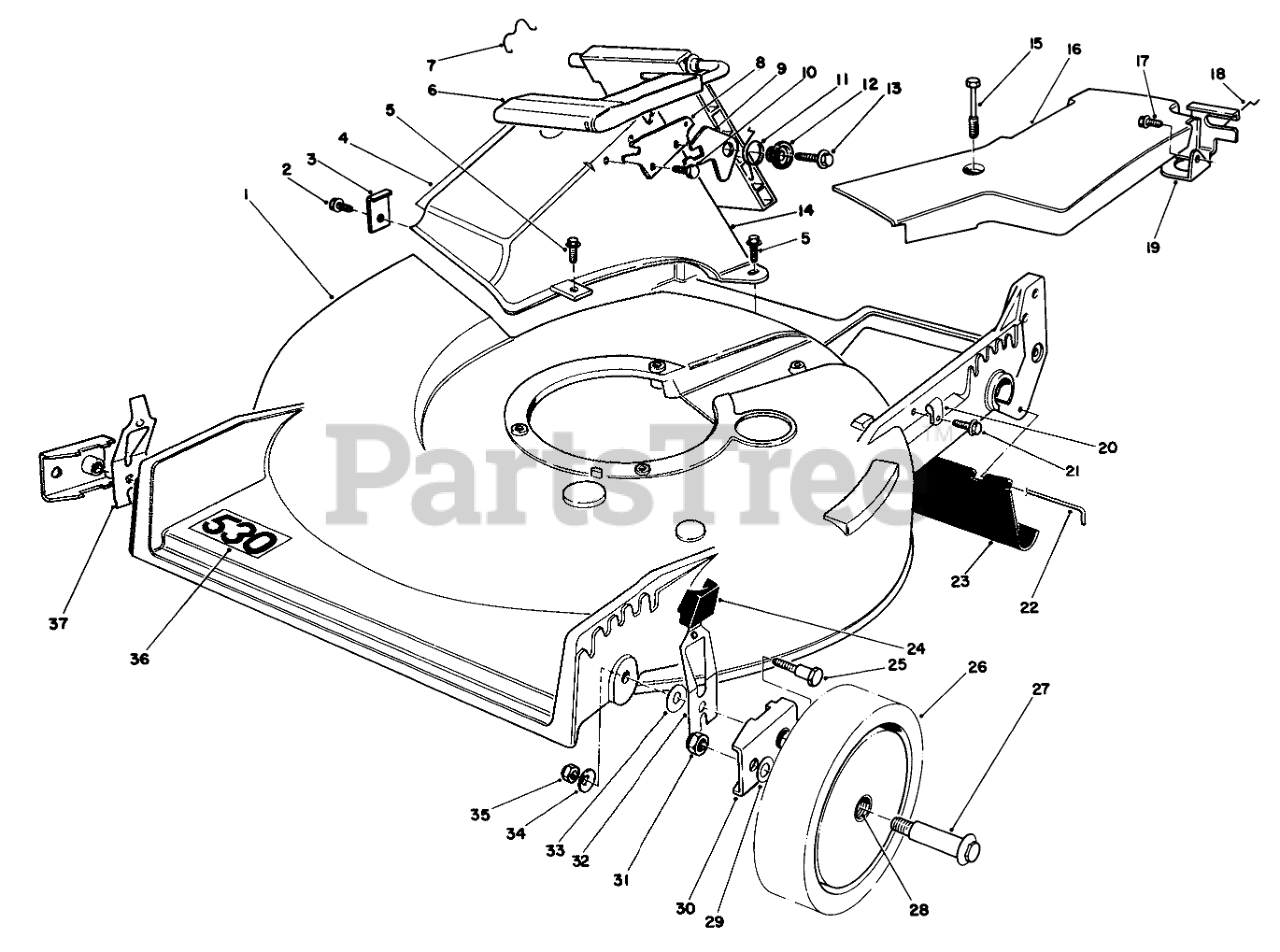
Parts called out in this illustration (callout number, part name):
1	21 SP RB HSG/DECAL
2	SCREW
3	TUNNEL CLIP
4	Decal-Attention
5	SCREW-HWH
6	Discharge Door Assembly
7	DOOR RET SPRING
8	DOOR LATCH PLATE
9	SAFETY LATCH
10	SCREW-PLASTITE
11	TORSION SPRING
12	DOOR SPACER
13	SCREW-HWH
14	Tunnel Discharge
15	SCREW-HHFTF
16	Cover-Belt
17	SCREW-HWHTF
18	RETAINER-CABLE
19	Bracket-Traction Adj.
20	CLAMP-CABLE
21	SCREW
22	ROD-SHIELD
23	SHIELD-TRAILING
24	KNOB-ARM
25	PIVOT SCREW
26	Wheel & Tire Assembly (Incl. Ref. #28)
27	WHEEL BOLT
28	BUSHING
29	WASHER
30	HP PIVOT ARM ASM
31	NUT-LOCK
32	L. HP SPRING ARM ASM
33	WASHER-PIVOT
34	WASHER-BELLEVILLE
35	NUT-LOCK, NI
36	Decal-530
37	R HP SPRING ARM ASM
